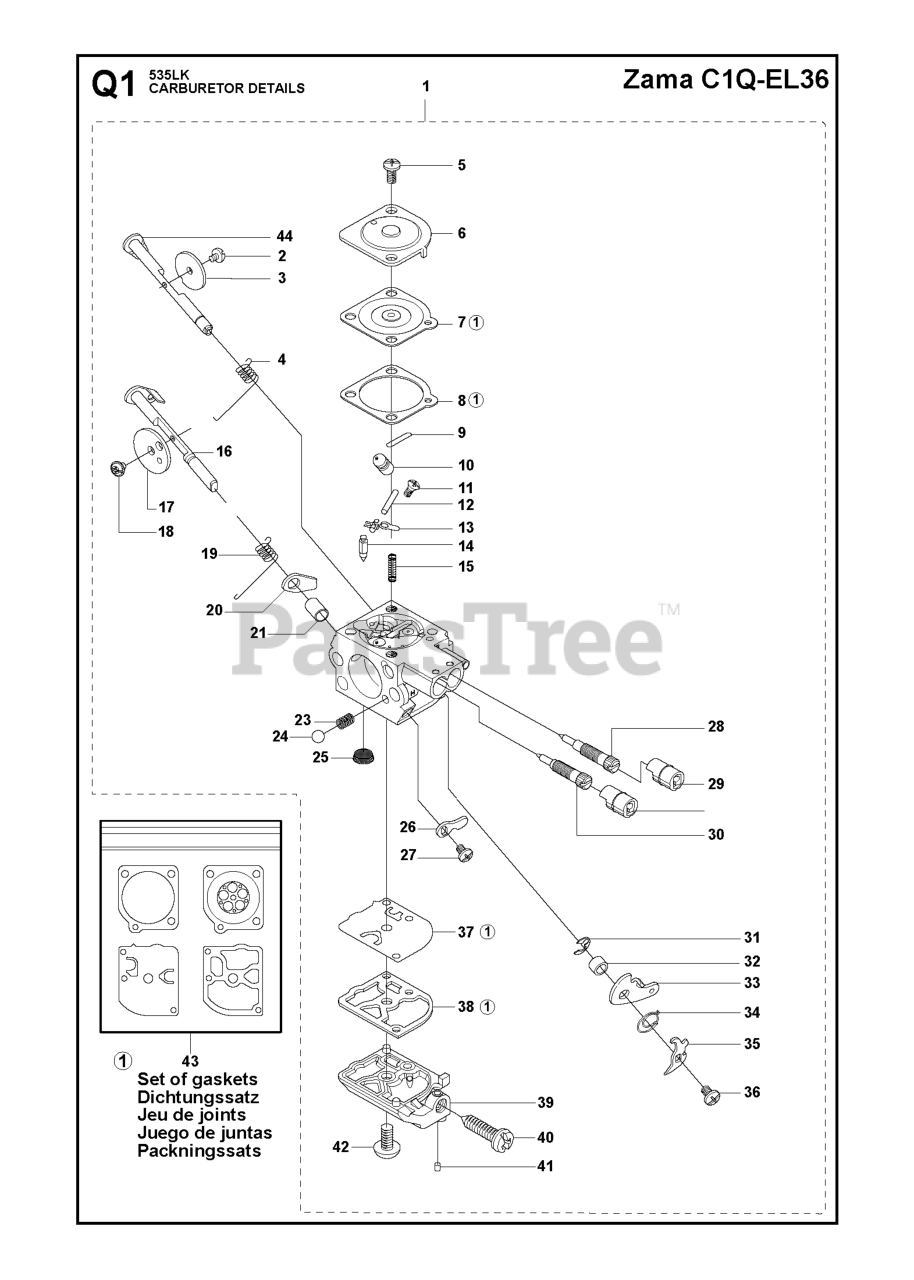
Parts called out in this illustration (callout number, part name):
1	CARBURETOR C1QEL36
4	RETURN SPRING
12	PIN RETAINING SCREW
14	INLET NEEDLE
15	SPRING
16	CHOKE SHAFT
17	DISC
25	FUEL INLET SCREEN
28	IDLE SCREW
29	LIMITER CAP KIT
34	SPRING
37	PUMP DIAPHRAGM
43	GASKET KIT (ZAMA GND39)
44	THROTTLE SHAFT
